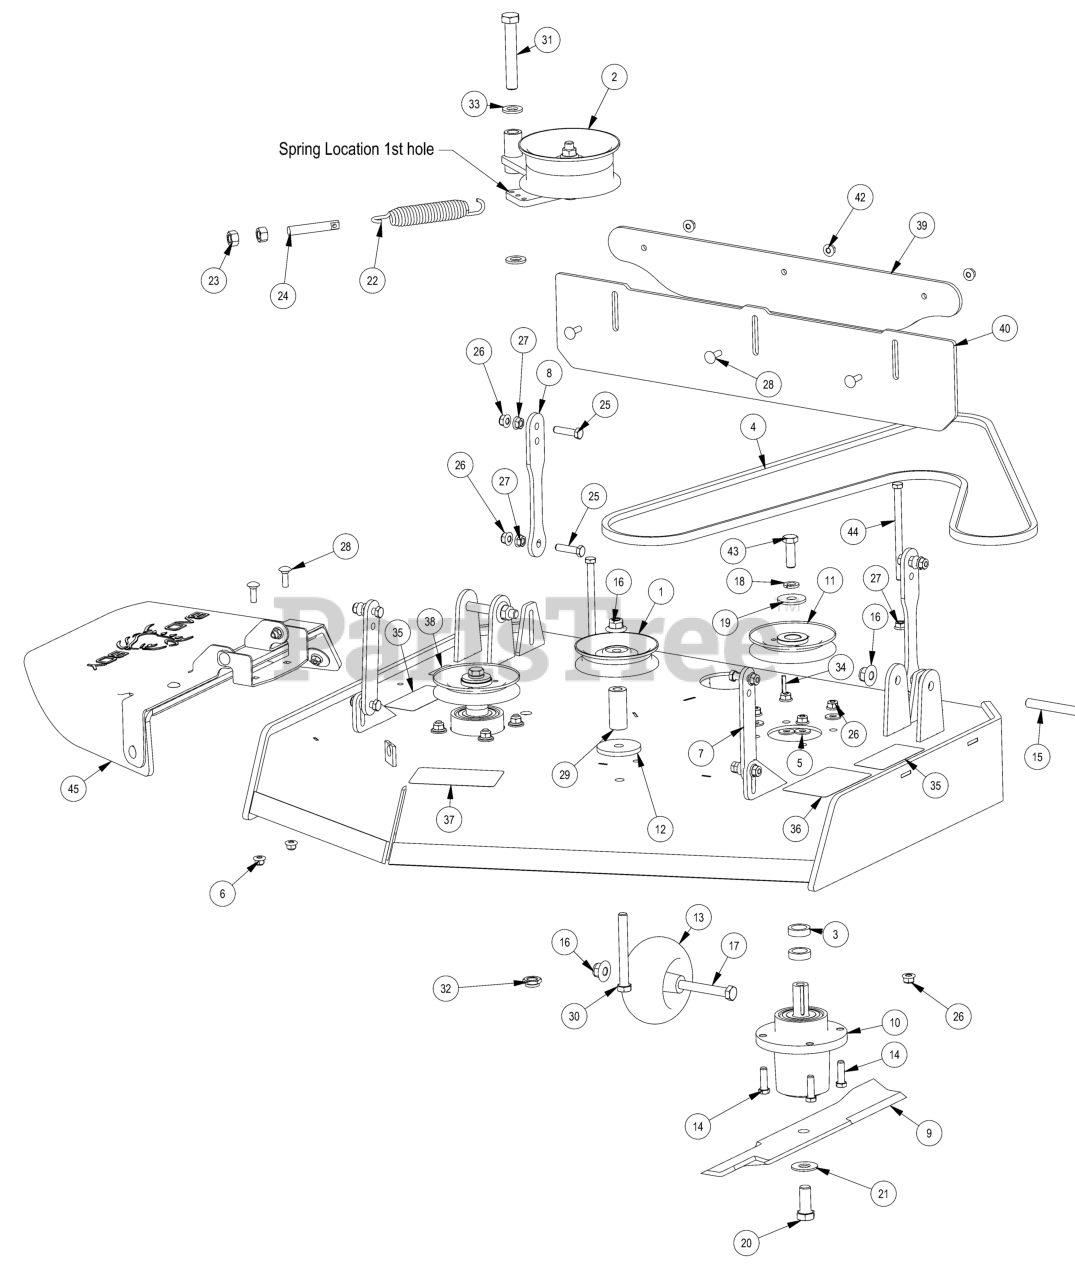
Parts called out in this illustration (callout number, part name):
1	5 V Idler Pulley 1/2" Bore
2	2020 36" Revolt Deck Idler Assembly
3	36 Deck Spindle Spacer
4	2020 Walk-Behind 36 Deck Belt
5	5/16 USS FLAT WASHER (7/8 OD) ZINC
6	5/16" Nylock Flange Nut Zinc
7	2019 Revolt Front Deck Hanger
8	2019 Stand-On Rear Deck Hanger
9	52" Deck Fusion Blade
10	36'' Revolt Spindle Assembly
11	MZ Deck Pulley
12	MZ Deck Idler Spacer
13	2019 Deck Wheel
14	3/8-16 X 1-1/4 HEX CAP SCREW (GR.5) ZINC
15	1/2-13 X 3-1/2 HEX CAP SCREW (GR.5) ZINC
16	1/2-13 NYLON INSERT FLANGE LOCKNUT ZINC
17	1/2-13 X 4-1/2 HEX CAP SCREW (GR.5) ZINC
18	1/2 SPLIT LOCKWASHER (GR.8) ZINC/YELLOW
19	1/2 BELLEVILLE WASHER (1-5/8 OD X .140 THK) ZINC
20	5/8-18 X 1-1/2 HEX CAP SCREW (GR.8) ZINC YELLOW
21	5/8 USS FLAT WASHER (1-3/4" OD) GR.8 ZINC YELLOW
22	2009 Deck/Pump Idler Spring
23	1/2-13 HEX NUT ZINC
24	All Thread
25	3/8-16 X 1-1/2 HEX CAP SCREW (GR.5) ZINC
26	3/8" Nylock Flange Nut
27	3/8-16 HEX SERRATED FLANGE NUT HARD/ZINC
28	5/16-18 X 1 CARRIAGE BOLT (GR.8) ZINC
29	2019 Revolt Stationary Idle Spacer
30	1/2-13 X 4-1/4 HEX CAP SCREW (GR.5) ZINC
31	5/8-11 X 4 HEX CAP SCREW (GR.8) ZINC YELLOW
32	5/8-11 NYLON INSERT JAM LOCKNUT ZINC
33	.630 ID Plastic Washer
34	3/16 X 1 SQ MACHINERY KEY 1018 STL ZINC
35	Danger Decal-Spindle/Discharge
36	2018 36" Deck Decal
37	Revolt Pump Belt Route Decal
38	Deck Impact Patent Decal 9591803
39	2023 4" & 5" Stripping Kit Plate
40	2023 MZ Stripping Kit Rubber
41	2023 36'' DECK
42	5/16" Flange Nut
43	1/2-20 X 1-1/2 HEX CAP SCREW (GR.5) ZINC
44	3/8-16 X 5-1/2 HEX CAP SCREW (GR.5) ZINC
45	2020 36 Stand On Discharge Assembly
